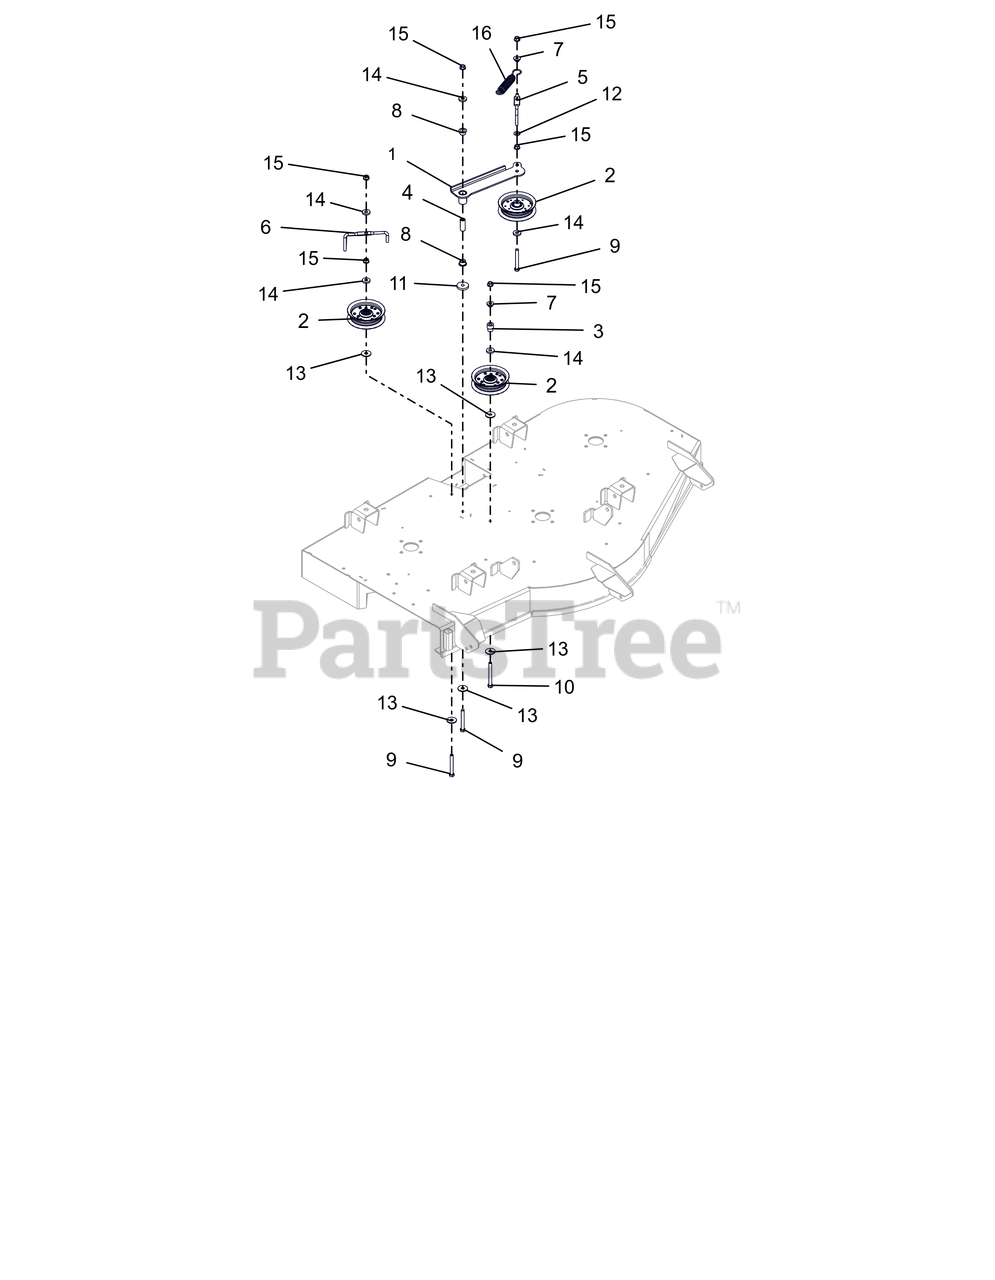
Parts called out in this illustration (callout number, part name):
1	WLDMT, IDLER ARM-52"
2	ASM, IDLER 4"
3	BUSHING, IDLER (P/M)
4	SPACER, .375IDX.625ODX1.66 PM
5	WIREFORM, BELT FINGER
6	WIREFORM, BELT FINGER
7	BSHG-FLG .385X.500X.875X.406
8	BSHG-FLG, .625X.750X.500X1.00
9	BLT-HEX .38-16X3.00 GR5 FTH YZ
10	@BLT-HEX .38-16X3.50 GR5 YWZC
11	WSHR,FLT STL.406X1.50X.245YWZC
12	WSHR, FLT .406X.812X.065 RAW
13	WSHR FL STL .406X1.25X.10ZC120
14	WSHR-FL-STL .406X1.00X.188 YWZ
15	NUT-LK-TOP-FLG .38-16 ZC120
16	SG-TENS .135X.98X6.0 WLD 62
